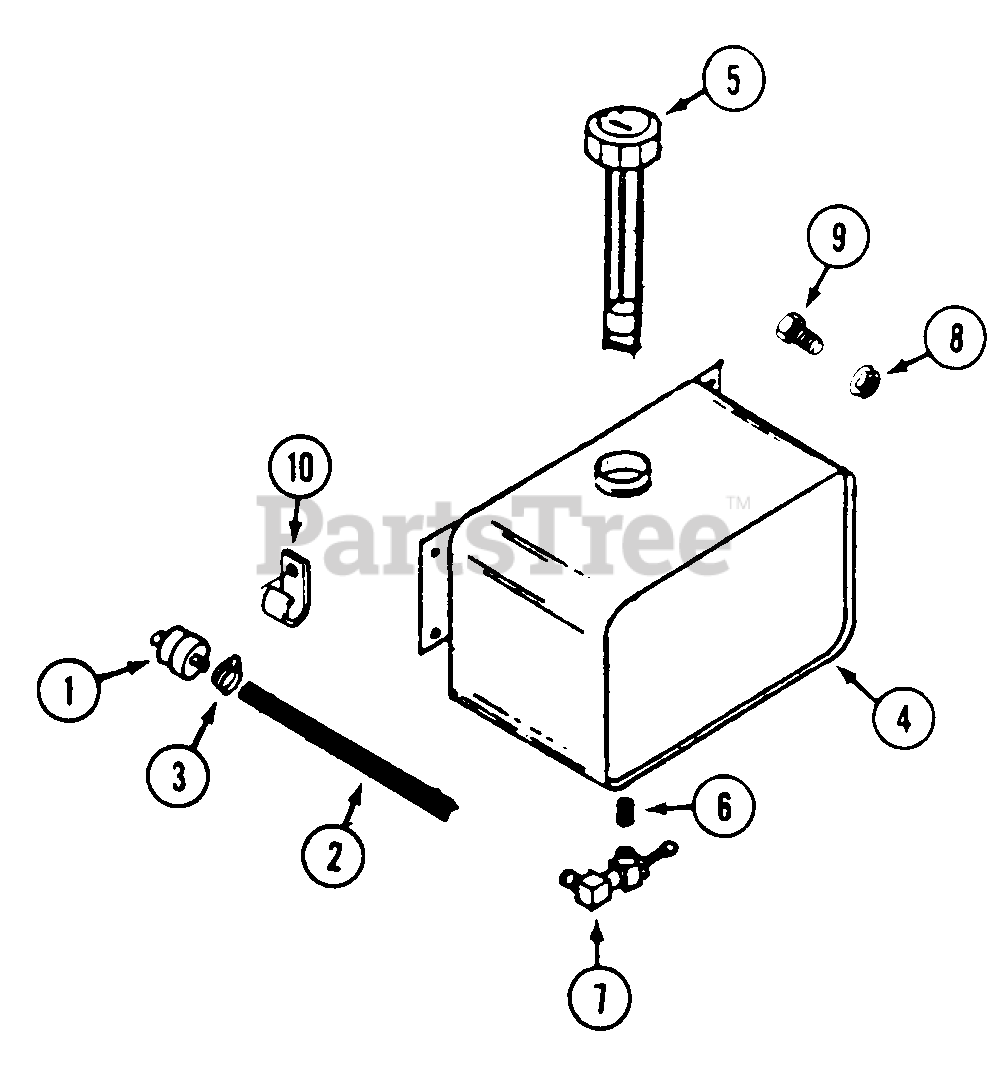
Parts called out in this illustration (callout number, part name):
1	FILTER - fuel
2	HOSE - fuel
5	CAP - fuel tank
6	NIPPLE - pipe 1/8"
7	VALVE - shut off
8	NUT - 1/4"-20 flange lock
9	BOLT - 1/4"-20 x 1/2"
9	BOLT - 1/4"-20 x 3/4"
10	CLIP - "J" fuel line
